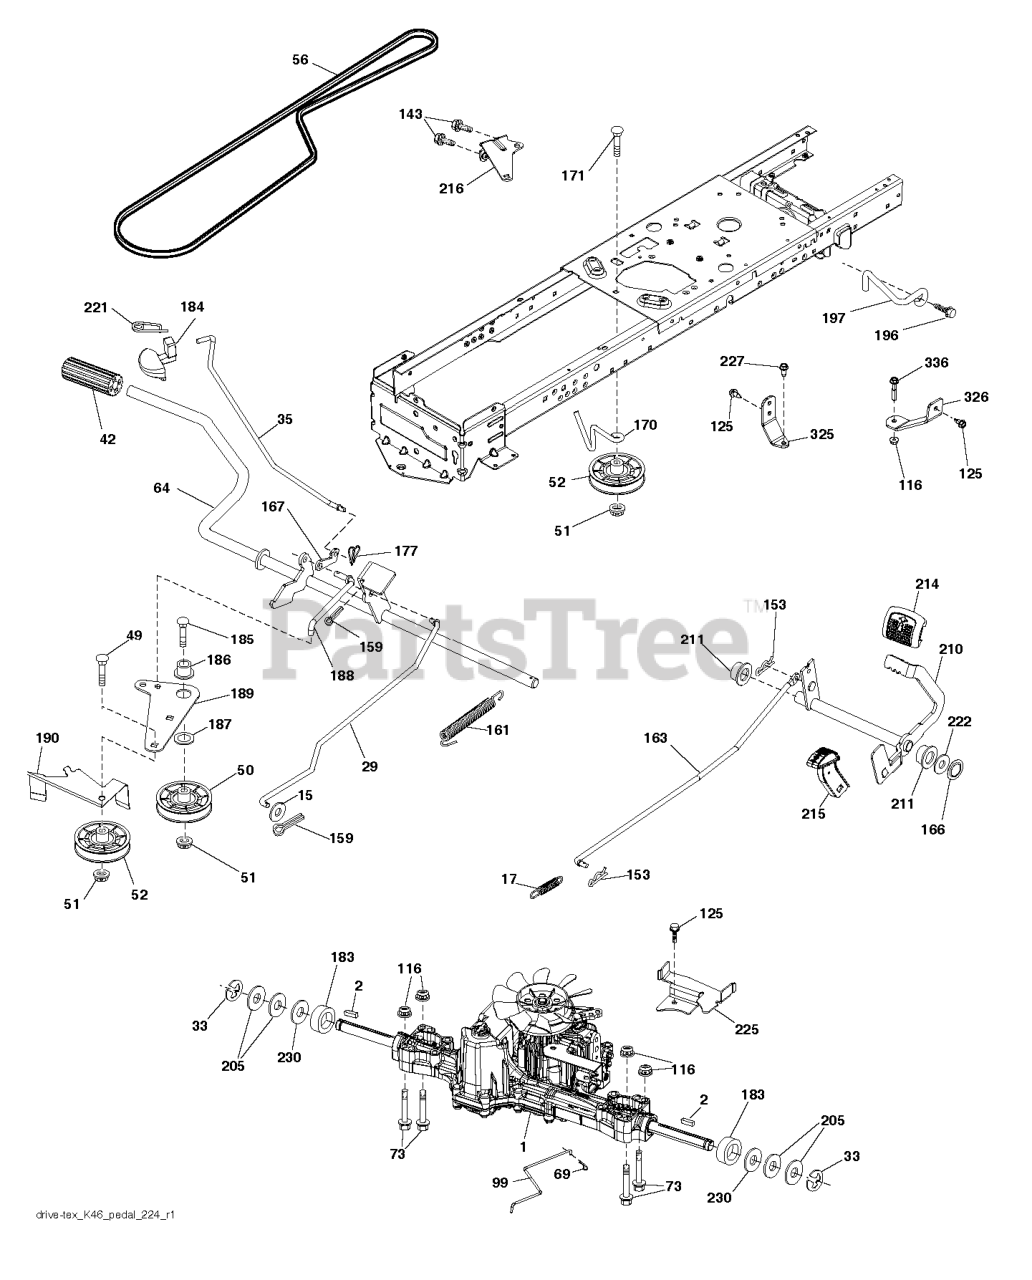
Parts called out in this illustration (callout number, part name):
2	SQUARE KEY
15	WASHER PLAIN WASHER 3/8 X 0.08
17	SPRING.BRAKE.K46.GREEN
29	ROD.BRAKE.K46
42	PEDAL COVER
50	IDLER.FLAT.910.OFFSET
51	NUT LOCK FLG 3/8-16 UNC
52	IDLER.V-GROOVE.910.OFFSET
64	SHAFT.ASM.PEDAL.BRK.CNTR
69	HAIRPIN.SOFT.ZINC.059X1.125
99	ARM.PIVOTING.TCRD.GEN2.5.BAGGE
125	SCREW
153	RETAINER M
161	SPRING, RETURN LT
166	NUT.PUSH.625
167	LATCH.BRAKE.SPRING
170	KEEPER.V-IDLER.CENTER.
177	PIN COTTER;LOCKING;BOWTIE;1IN
183	SPACER AXLE
184	HANDLE.PARKING.BRAKE.H (BLK)
186	SPACER.RETAINER
188	LINK.CLUTCH.GROUND DRIVE.LONG
189	BELLCRANK.GROUND.DRIVE.TEX.
190	KEEPER.BELLCRANK.DRIVE
196	SCREW 3/8-16X1
210	ROCKER.ASM.PEDAL.CONTR
211	BEARING.NYLON
214	PEDAL.FORWARD.PAD.TEX
215	PEDAL.COVER.REVERSE.CRD.X428BK
216	BRACKET.PULLEY.IDLER.W/TEX
221	RETAINER.SPRING.CLIP.H
222	WASHER 21/32 X 1-1/4 X 10 GA.
225	KEEPER.BELT.TRANSAXLE.K46
230	WASHER.HARDENED
325	BRACKET.TRQ.STP.46.20".TIRE.LH
326	BRCKT.PNT.TRQ.STP.46.20TIRE.RH
